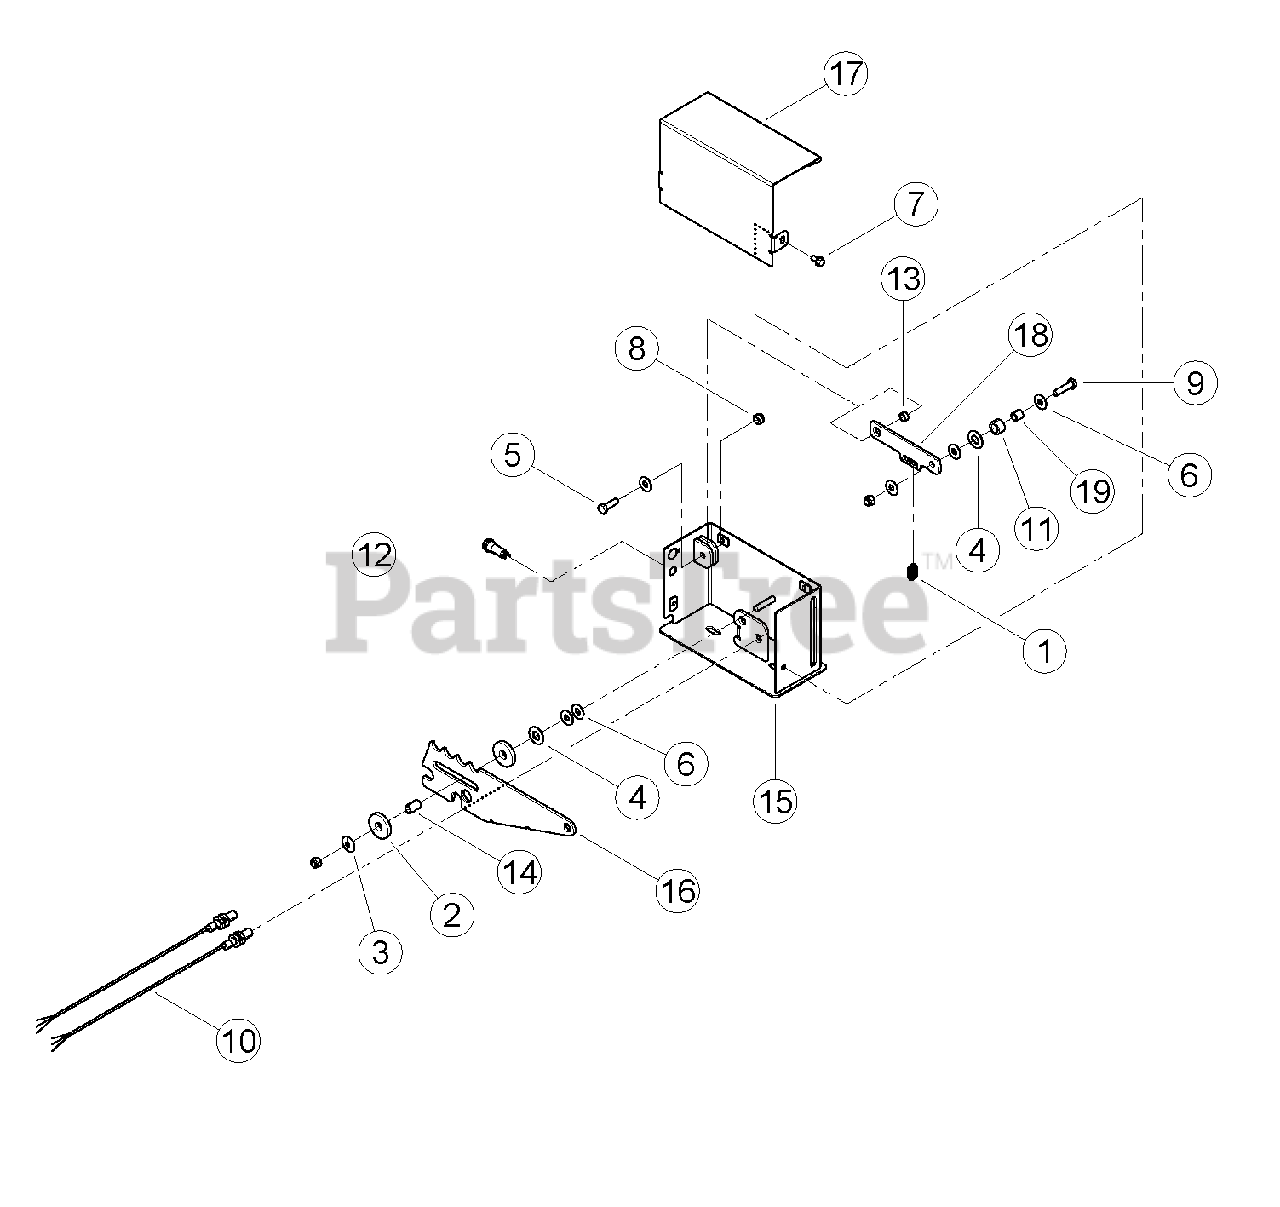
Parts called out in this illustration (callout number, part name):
1	SPRING, CONTROL BAR
2	WASHER, UHM SPACER .515 ID X 1.50 OD
3	WASHER, SPRING
4	WASHER, 1/2 SAE FLAT ZP
5	BOLT, 5/16 X 1 HHCS GR5 NC ZP
6	WASHER, 5/16 FLAT ZP
7	BOLT, 1/4 X 1/2 SERRATED FLANGE GR5 ZP
8	NUT, 5/16 NYLOCK
9	BOLT, 5/16 X 1-1/4 HHCS GR5 NC ZP
10	SENSOR, PROXIMITY
11	ROLLER, NYLON .750 OD X .502 ID X .440
12	LED, TRI-COLOR 12V 3-TERMINAL BASE
13	SPACER, IDLER PIVOT
14	SPACER, .50 X .775
15	WELDMENT, SWITCH BOX
16	BAR, SWITCH CONTROL
17	COVER, CONTROL BOX
18	LINK, DETENT
19	SPACER, .50 OD X .35 ID X .47
